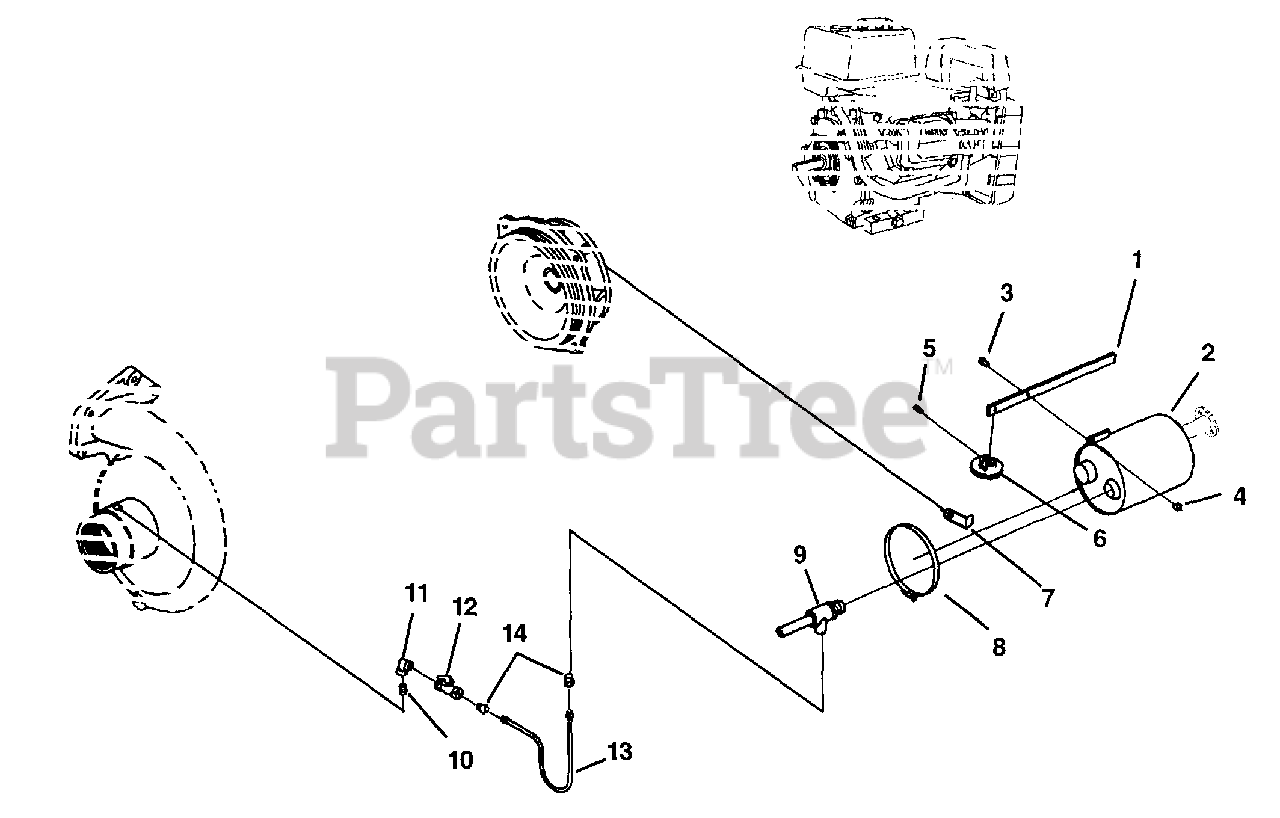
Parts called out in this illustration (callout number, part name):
1	LEVER-Prime
2	MUFFLER
3	SCREW-Hex Hd. (1/4-20 x 3/4)
4	NUT-Locking Hex
5	PIN-Spirol
6	VALVE-Flapper
7	BRACE-Muffler
8	STRAP-Muffler
9	VENTURI-Priming
10	NIPPLE-Close (1/4")
11	FITTING-Street
13	LINE-Vacuum
14	Connector 45° Flare
